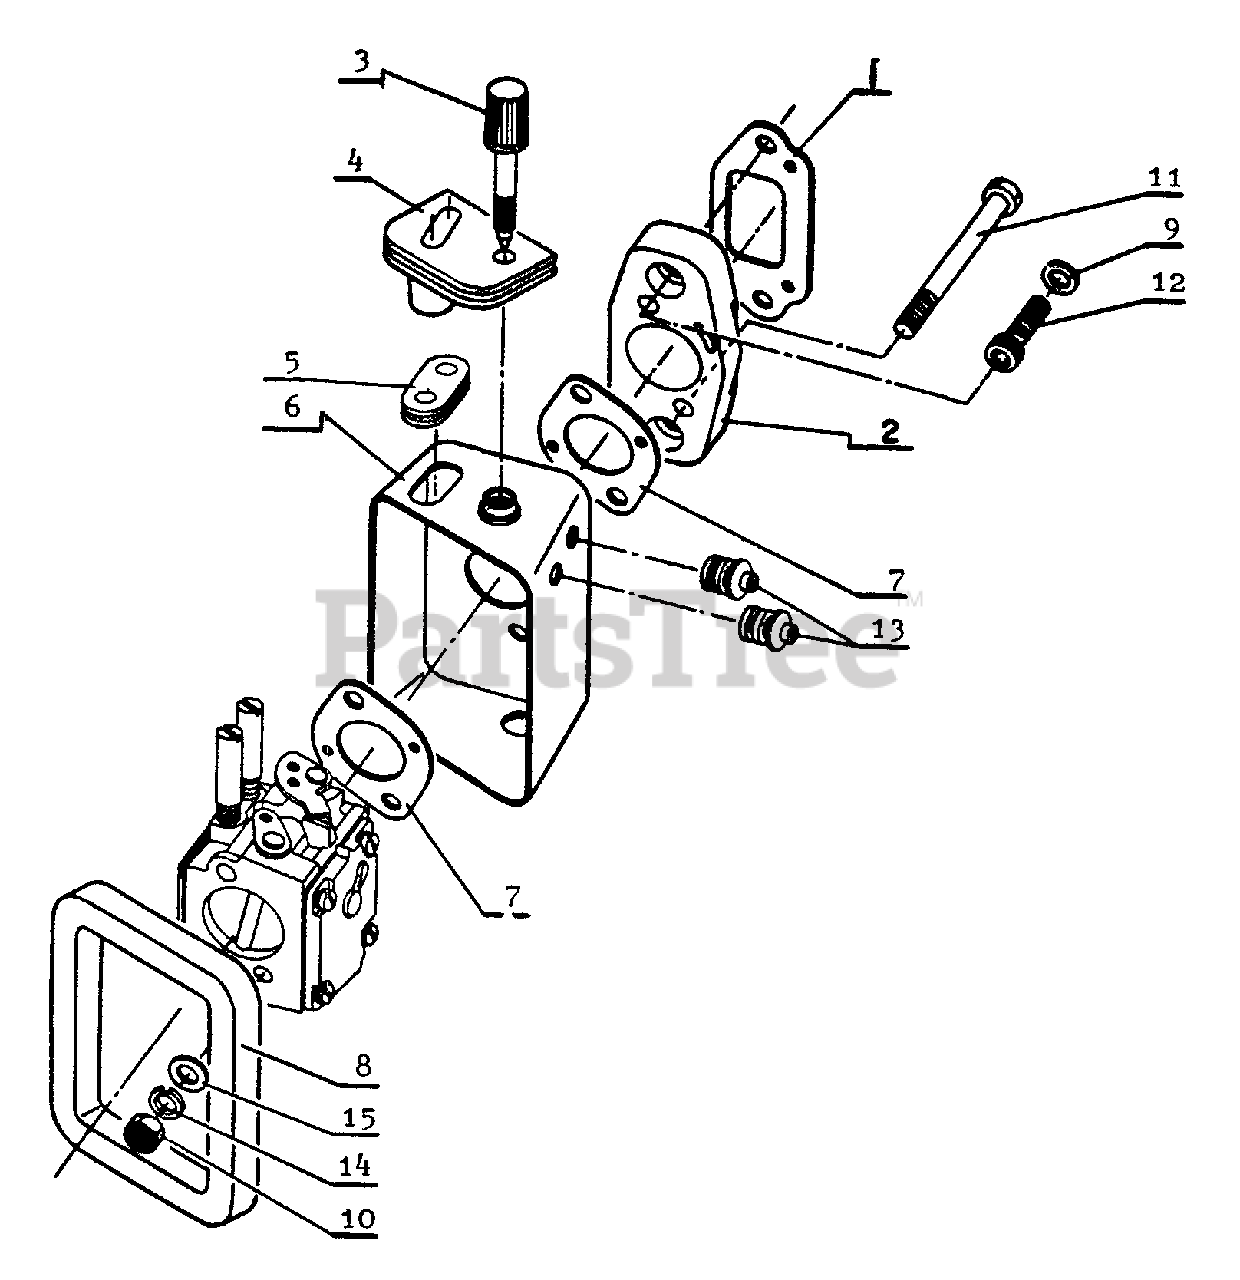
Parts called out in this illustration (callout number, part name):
1	GASKET, INTAKE
2	INSULATOR
3	SCREW, IDLE ADJUST
4	GROMMET
5	GROMMET
6	CASE, CARBURETOR
7	GASKET, INTAKE
8	GASKET, CARBURETOR CASE
9	WASHER - 5
10	LOCKNUT - 5
11	BOLT
12	SCREW - 5X25
13	GROMMET
14	LOCKWASHER - 5
15	WASHER - 5
